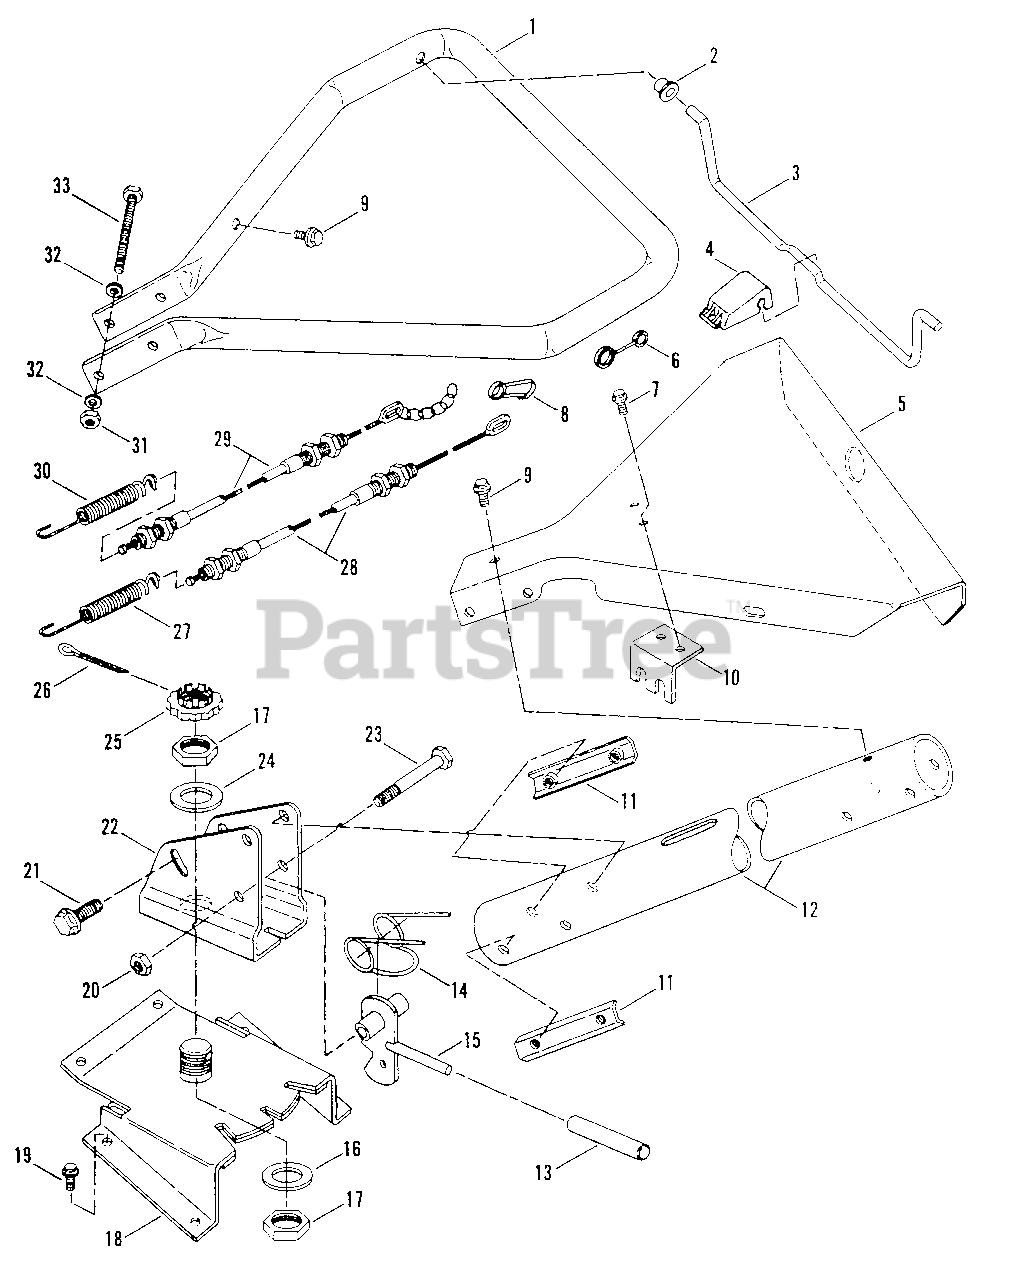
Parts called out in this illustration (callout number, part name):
1	BAR, Handle
2	BUSHING
3	(NLA) BAIL
4	CLIP, Cable
5	PANEL, 5 HP
6	(NLA) LINK, Wire 2.25"
7	SCREW, 1/4-20 x 1/2" Self-Tapping
8	CLIP-SNAP
9	SCREW, 5/16-18 x 1/2" Self-Tapping
10	(NLA) BRACKET
11	(NLA) PLATE, Tap
12	(NLA) TUBE, Handle Bar Support
13	GRIP, Handle
14	SPRING
15	(NLA) WELDMENT, LATCH RTT
16	WASHER, Flat .77 x 1.13 x .06
17	NUT, 3/4-16 Hex Lock
18	BRACKET, Latch
19	SCREW, 5/16-18 x 5/8" Self-Tapping
20	NUT, 3/8-24 Hex Center Lock
21	BOLT, 3/8-16 x 3/4" Hex Flange Lock
22	BRACKET, Handle
23	SCREW, 3/8-24 x 2 1/2" Hex Head Cap
24	WASHER, 13/16 Flat
25	RETAINER, Nut Locking
26	COTTER-PIN, 5/32 x 1 1/4"
27	SPRING, Traction Cable
28	CABLE, Traction Control
29	CABLE, Tine Control
30	SPRING, Tine Cable
31	NUT, 5/16-18 Hex Lock
32	WASHER, 5/16 Flat
33	SCREW, 5/16-18 x 3" Hex Head Cap
